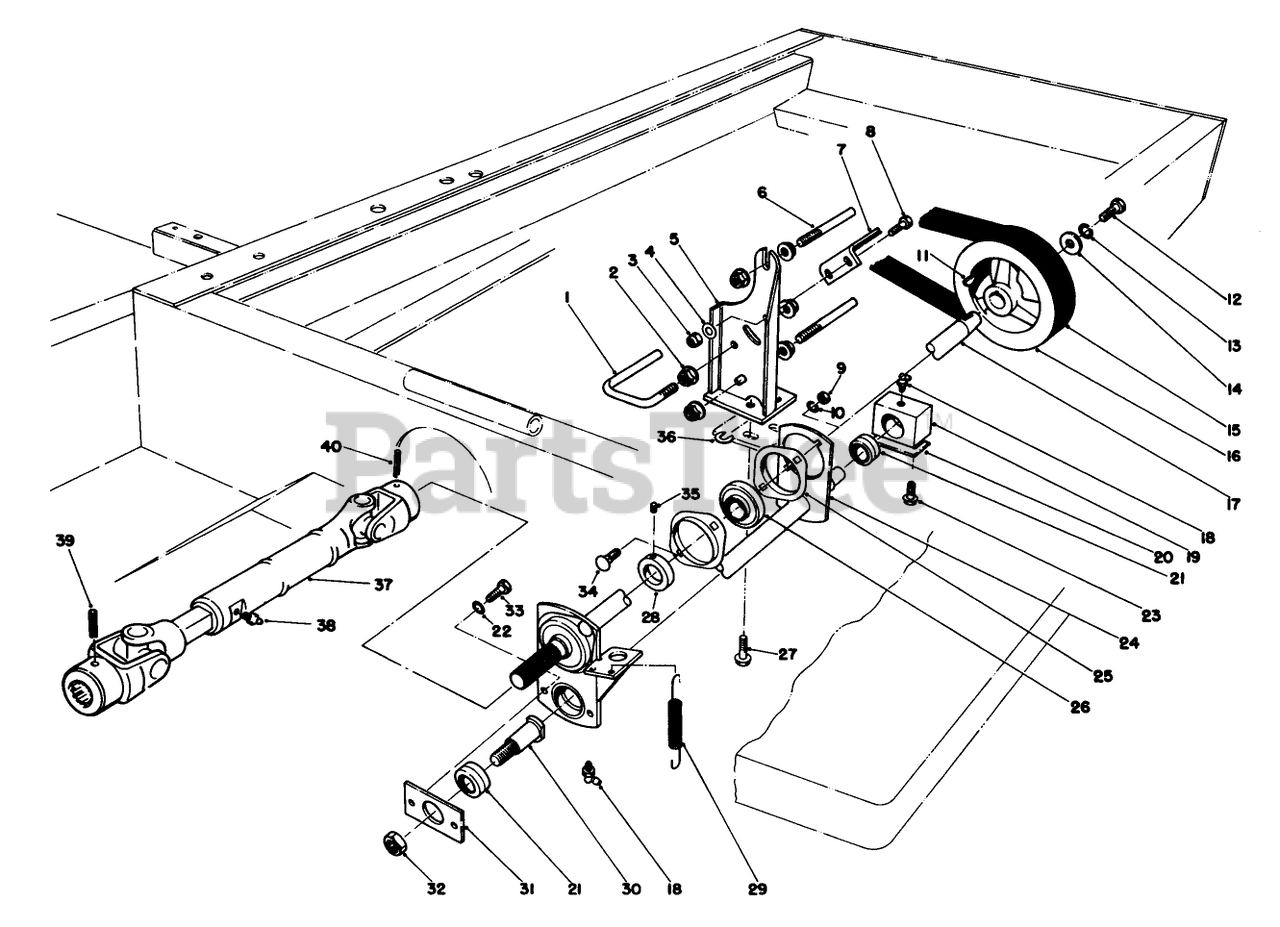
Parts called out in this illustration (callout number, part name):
1	LOWER BELT GUIDE
2	NUT-HHF, WHIZ
3	NUT-LOCK, NI
4	WASHER-PLAIN
5	Bracket-Brake
6	UPPER BELT GUIDE
7	PTO SUPT PAD ASM
8	SCREW-HH
9	NUT-HEX
10	WASHER-LOCK
11	KEY-WOODRUFF
12	SCREW-HH
13	WASHER-LOCK
14	WASHER-FLAT
15	V-BELT
16	Pulley-PTO
17	PTO SHAFT
18	FITTING-GREASE, 90 DEG
19	BEARING HUB PP
20	PTO SHIM BLOCK
21	BEARING
22	WASHER-LOCK
23	SCREW-HHF
24	ARM WA - ENGAGE R
25	FLANGE
26	Bearing w/Collar (Incl. Ref. #28 & 35)
27	SCREW-HHF
28	COLLAR-LOCK, BEARING
29	TENSION PTO SPRING R
30	BEARING STUD
31	BRG RETAINER
32	NUT-LOCK, NI
33	SCREW-HH
34	SCREW-CARR
35	SCREW-SET, HSH
36	SPECIAL WASHER
37	UNIVERSAL JOINT
38	FITTING-GREASE
39	PIN-ROLL
40	ROLL PIN
